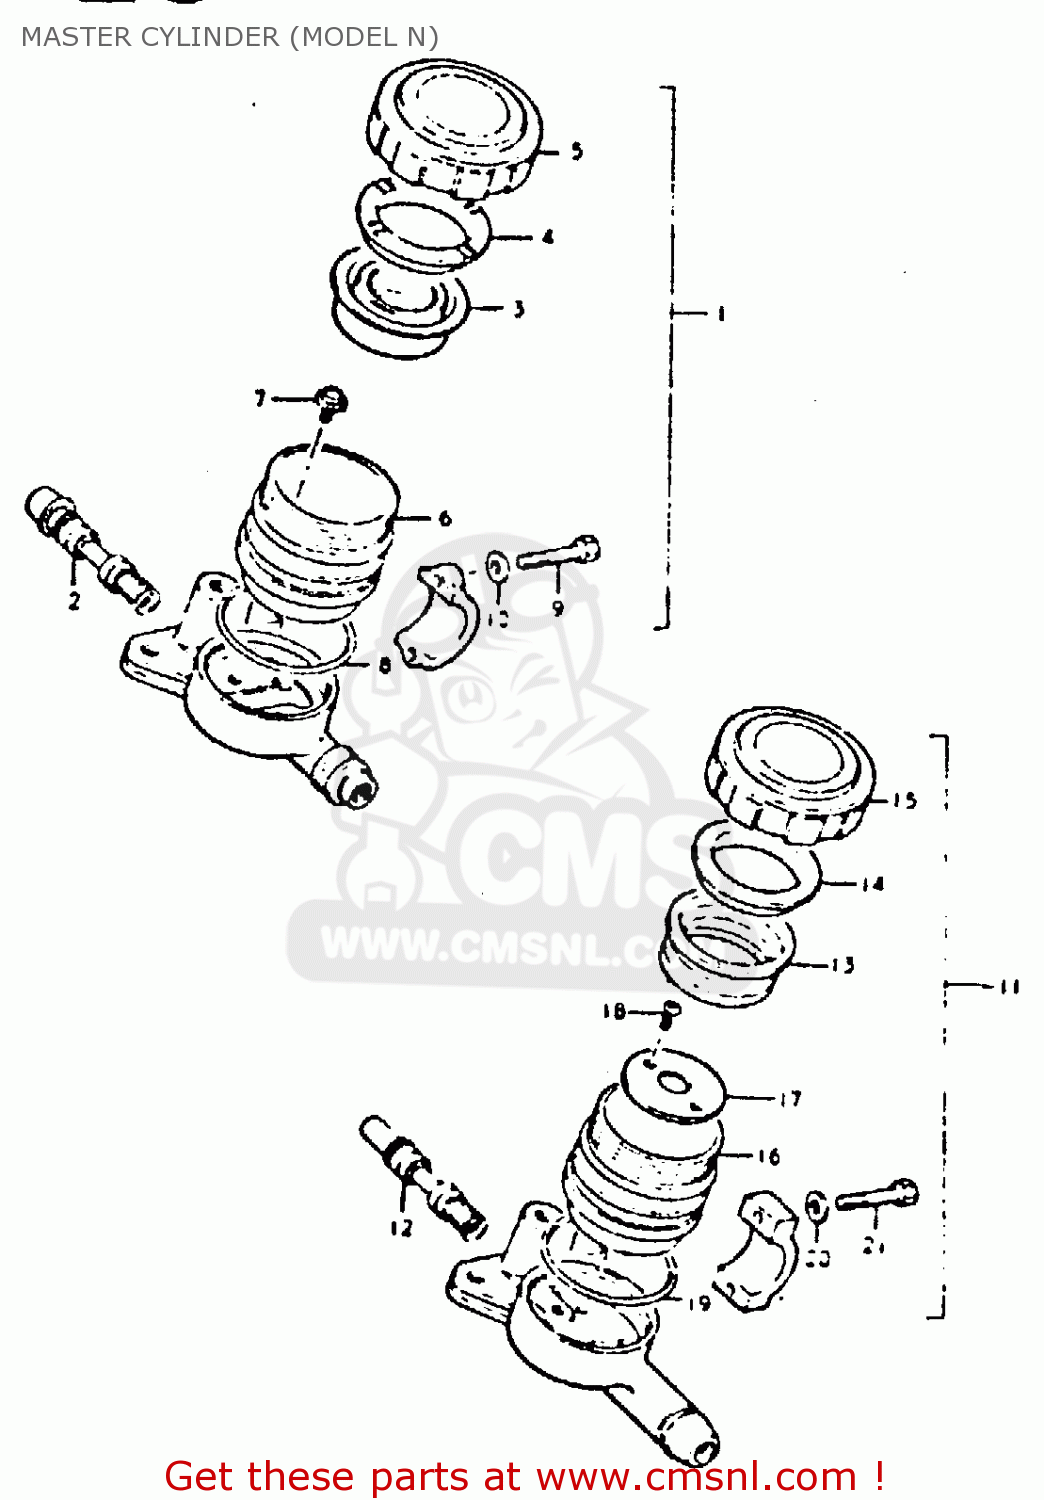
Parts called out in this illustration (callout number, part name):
1	CYLINDER ASSY, MASTER
2	PISTON & CUP SET
3	DIAPHRAGM
4	PLATE
5	CAP
6	RESERVOIR
7	SCREW,MASTER CYLINDER
8	O RING
9	BOLT
10	WASHER
11	CYLINDER ASSY,
12	PISTON & CUP SET
13	DIAPHRAGM,MASTER CYLINDER
14	PLATE,DIAPHRAGM
15	CAP
16	RESERVOIR
17	PLATE
18	SCREW
19	O RING
20	WASHER
21	BOLT
